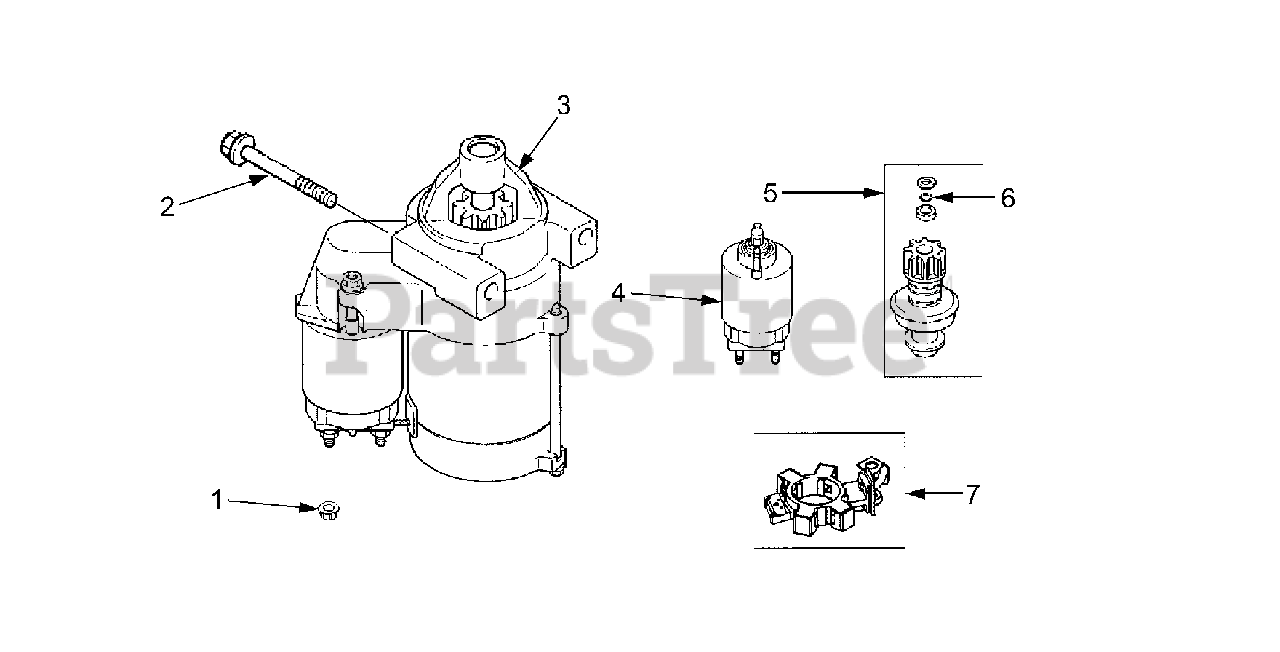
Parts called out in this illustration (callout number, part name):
1	Nut, Hex Flange M8 x 1.25"
2	Screw, Hex Flange M8 x 1.25 x 80
3	Starter, Solenoid Shift Assembly
4	Kit, Solenoid
5	Kit, Pinion Drive
6	Ring, Retainer
